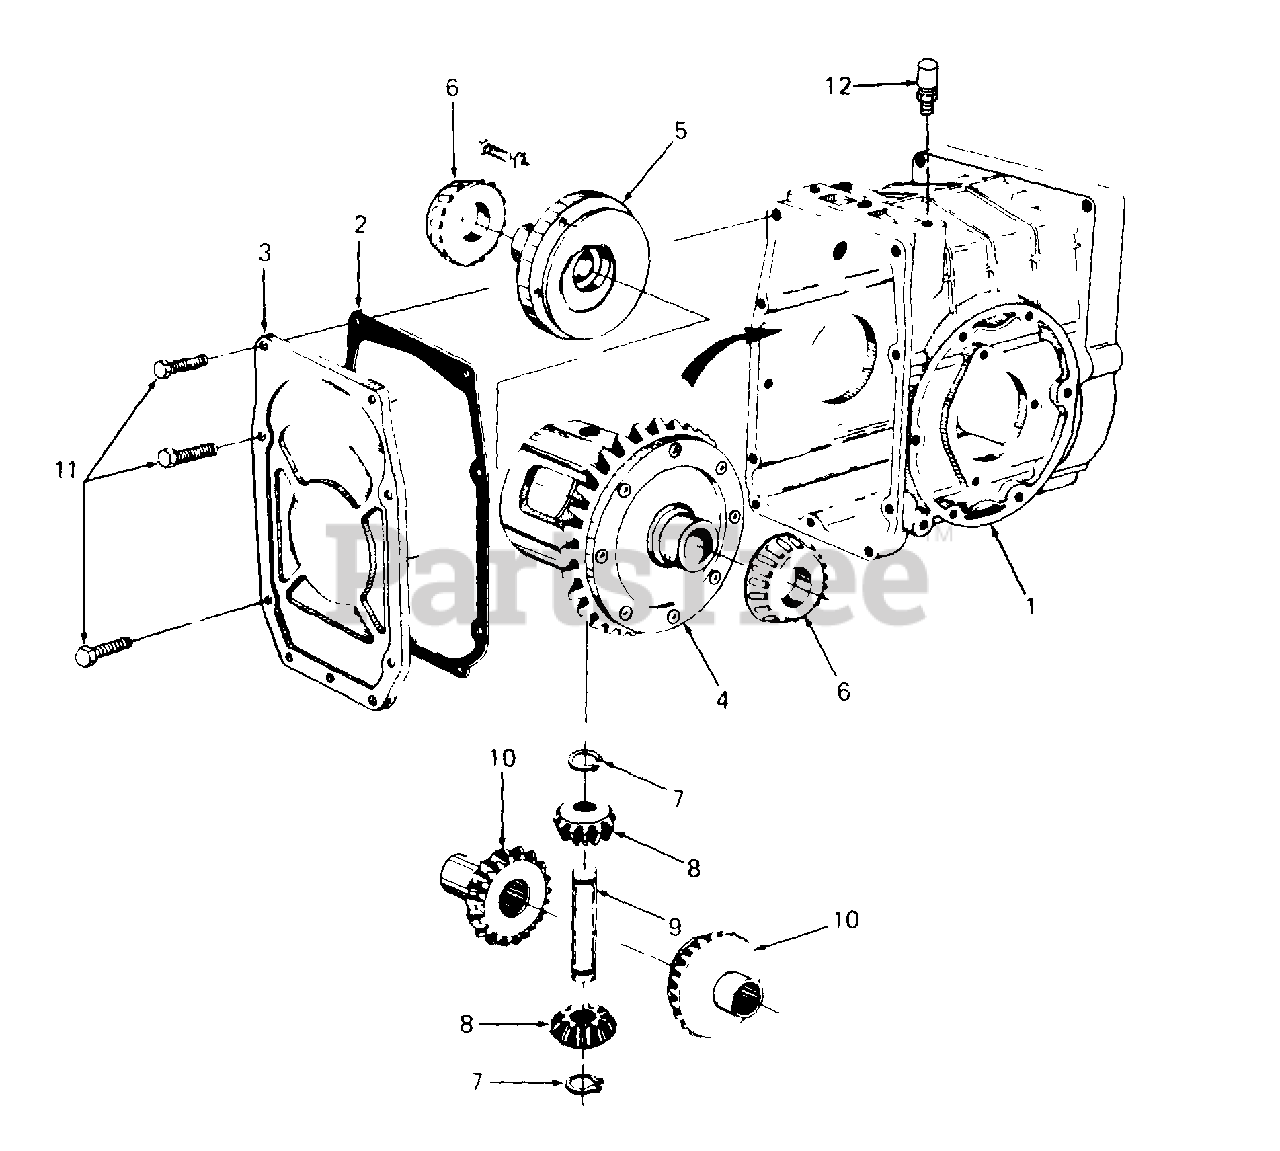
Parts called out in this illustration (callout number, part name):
1	Housing Assy, Rear Transaxle
2	Gasket, Rear Cover
3	Plate, Rear Cover
4	Gear Assy, Ring w/Case
5	Plate, Differential Flange
6	Cone, Roller Brg
7	Ring, Retaining, 11/16
8	Gear, Pinion - 10T
9	Shaft, Cross
10	Gear, Side - 16T
11	Bolt, Hex Patch, 318-16 X .62 Lg GR5
